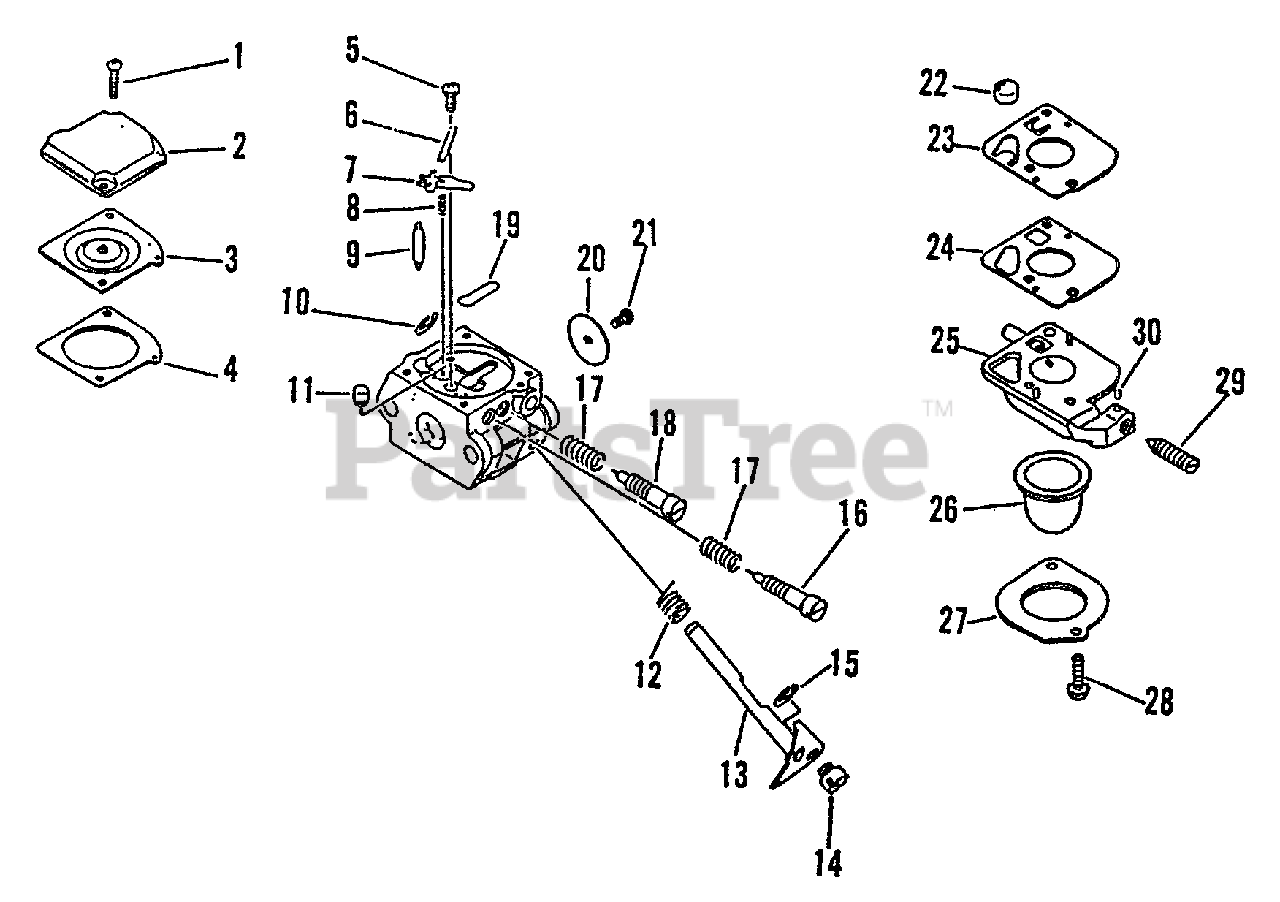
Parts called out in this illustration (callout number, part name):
2	COVER, METERING
3	DIAPHRAGM
4	GASKET, METERING
5	SCREW, METERING LEVER PIN
6	PIN
7	LEVER, METERING
8	SPRING
9	VALVE, NEEDLE
10	RING, RETAINING
11	NOZZLE, CHECK VALVE
12	SPRING, RETURN
13	SHAFT, THROTTLE
15	RING, RETAINING
16	NEEDLE - MIXTURE
18	NEEDLE - HIGH SPEED
19	PLUG, WELCH
20	VALVE, THROTTLE
22	STRAINER
23	DIAPHRAGM, PURGE
24	GASKET, PURGE
25	BASE, PURGE
26	BULB, PURGE
27	RETAINER, PURGE BULB
28	SCREW, RETAINER
29	SCREW, IDLE ADJUST
30	PIECE, FRICTION
